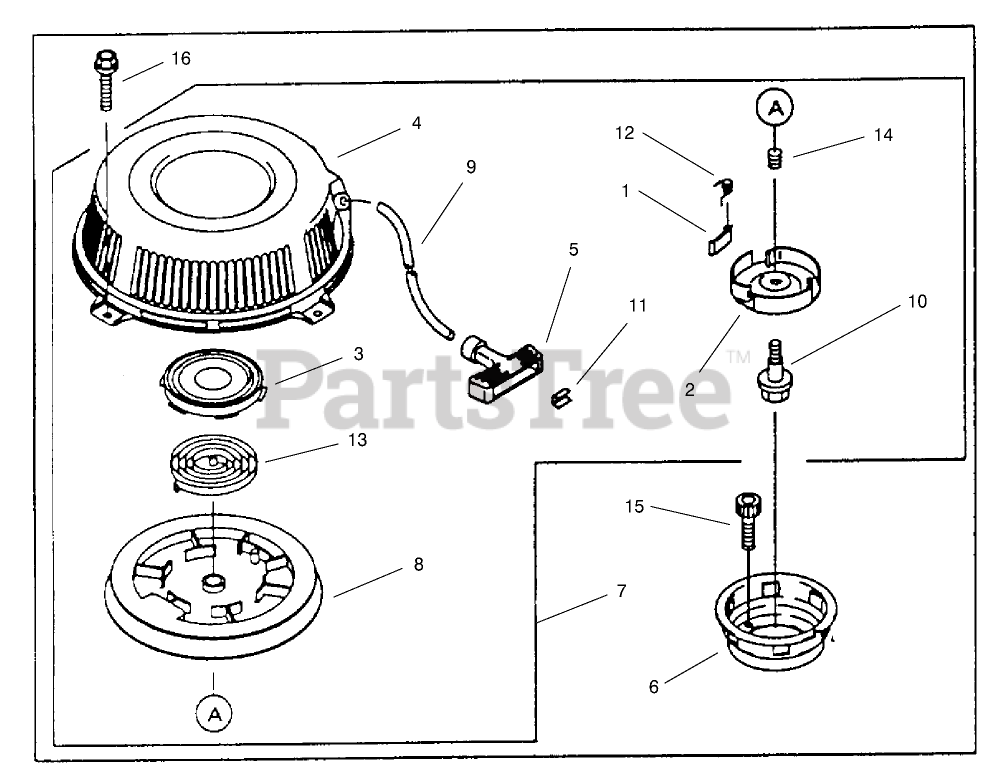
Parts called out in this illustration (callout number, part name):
1	Pawl
2	Retainer
3	Case
4	Case-Recoil Starter
5	Grip
6	Pulley-Starting
7	Starter-Recoil
8	Reel
9	Rope
10	Bolt
11	Washer
12	Spring
13	Spring
14	Spring
15	Bolt-Socket
16	BOLT-FLANGED (6X10)
